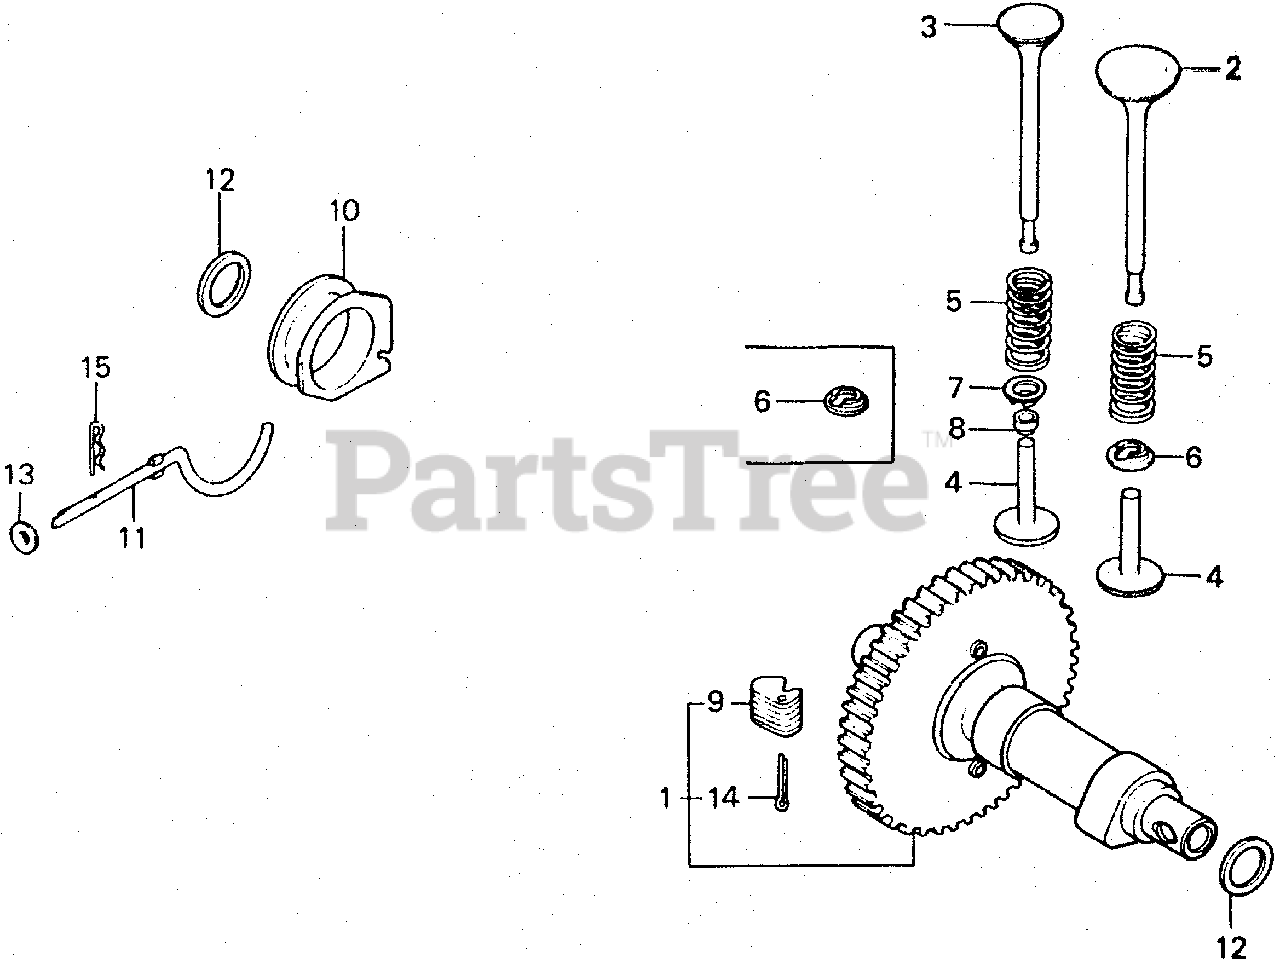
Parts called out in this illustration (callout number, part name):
1	CAMSHAFT ASSY.
2	VALVE, IN.
3	VALVE, EX.
4	LIFTER, VALVE (45.89MM)
4	LIFTER, VALVE (46.04MM)
4	LIFTER, VALVE (46.19MM)
4	LIFTER, VALVE (46.34MM)
5	SPRING, VALVE
6	RETAINER, VALVE SPRING
7	RETAINER, VALVE SPRING
8	ROTATOR, EX. VALVE
9	WEIGHT, GOVERNOR
10	SLIDER, GOVERNOR
11	SHAFT, GOVERNOR
12	WASHER, THRUST (18MM)
13	WASHER, PLAIN (6MM)
14	PIN, COTTER (3.0X45)
15	PIN, LOCK (10MM)
